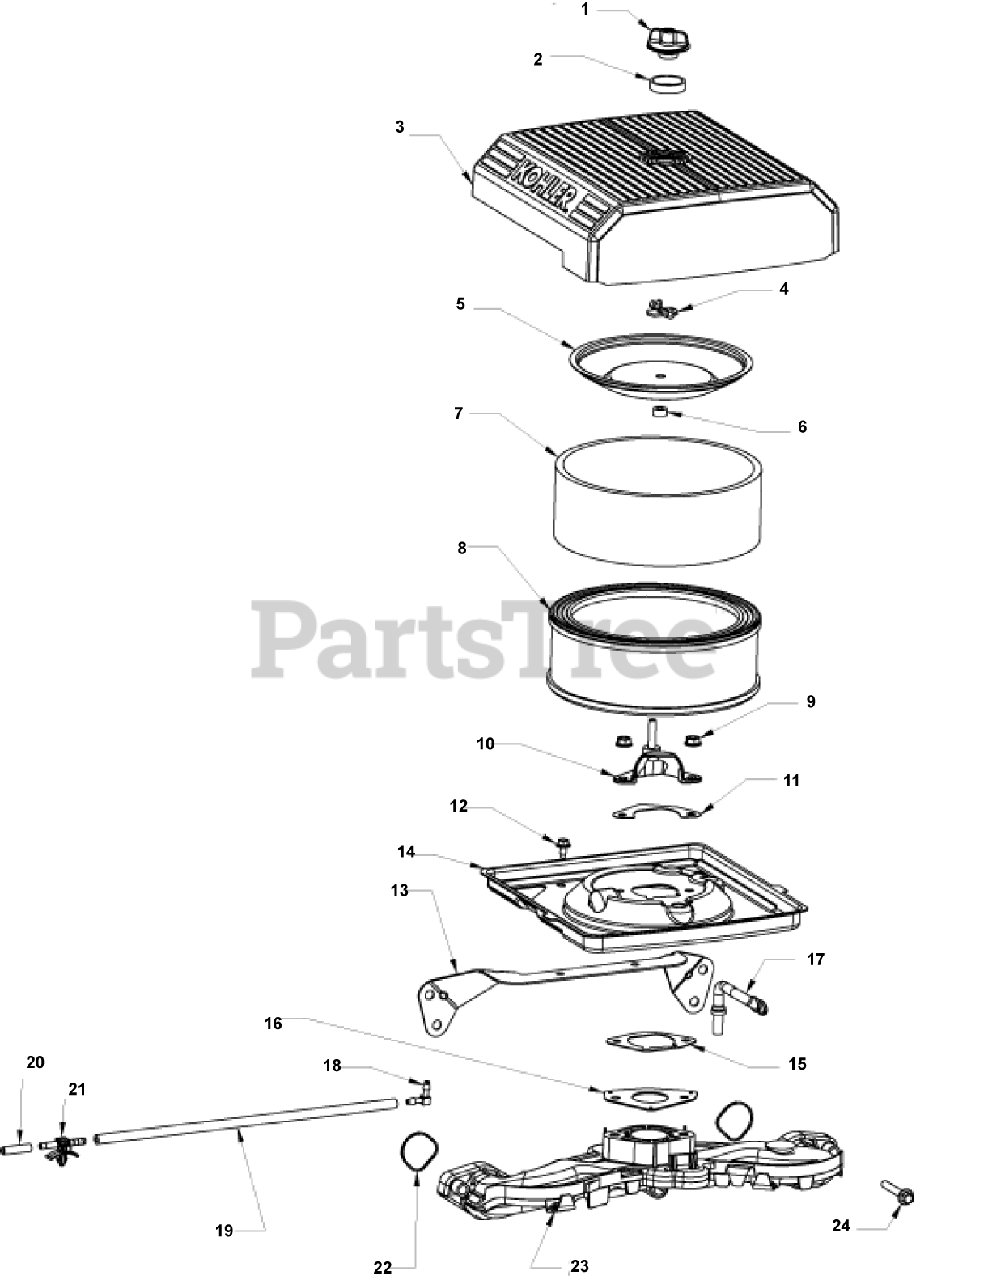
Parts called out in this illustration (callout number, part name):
1	KNOB, COVER
3	COVER, AIR CLEANER
4	NUT, WING
5	COVER, INNER AIR CLEANER
6	SEAL, BREATHER
7	PRE-CLEANER (HIGH)
8	ELEMENT, AIR FILTER (HIGH) - Also available Retail Packaged 24 883 03-S1 Air Filter Kit
9	NUT, FLG M6X1.0
10	CUP, FUEL SPITBACK W/O NIPPLE
11	GASKET, FUEL SPITBACK CUP
12	SCREW, FLG THD FRM M5X.8X10
13	BRACKET, AIR CLEANER BASE
14	KIT, AIR CLEANER BASE
15	GASKET, AIR CLEANER BASE
16	GASKET, CARBURETOR
17	HOSE, EVAPORATIVE-USE 24 326 131-S
18	CONNECTOR, EVAPORATIVE HOSE
19	HOSE, EVAPORATIVE 20"
20	CAP, MASKING
21	CONNECTOR, EVAPORATIVE
22	O-RING, INTAKE PORT
23	KIT, INTAKE MANIFOLD USE 24 164 266-S
24	SCREW, FLG M6X1.0X40
5475501-S	KIT, KNOB W/SEAL
